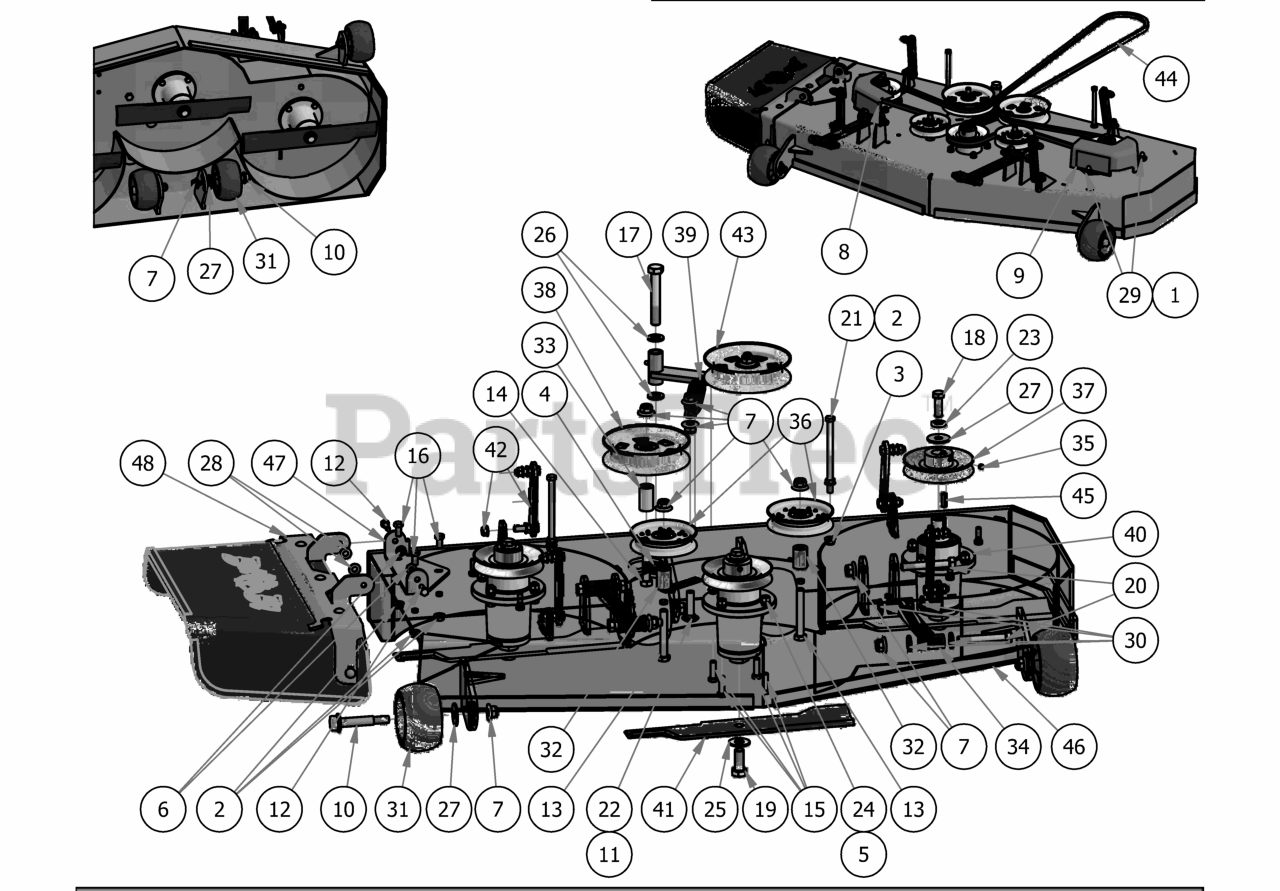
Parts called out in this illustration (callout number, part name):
1	Acorn nut-pulley Cover
2	3/8" Flange Nut
3	3/8" Nylock Flange Nut
4	5/8-11 Nylon Insert Jam Half Nut
5	3/8" Hex Nut
6	5/16" Nylon Flange Nut
7	1/2-13 Nylon Flange Nut
8	pulley cover chute side
9	pulley cover non-chute side
10	Deck Wheel Bolt
11	1/2 x 2" Carriage Bolt
12	5/16-18 x 1 GR 5 Hex Bolt Zinc
13	1/2 x 3 1/2 Flange Bolt Grade 8
14	1/2" x 4" Bolt (Grade 8)
15	3/8" x 1 1/4" Hex Bolt
16	3/8" x 3/4" Hex Bolt
17	5/8" x 4" Hex Bolt
18	1/2"-20 x 1 1/2 - Grade 5 Fine Thread Bolt
19	5/8 x 1 1/2 Grade 8 Hex Bolt (Fine)
20	1/2-13 x 3 1/2 GR 5 Hex Bolt
21	3/8-16 x 5 1/2 Hex Bolt
22	.517 Square Hole Round Washer
23	1/2" Lock Washer Zinc
24	3/8" Lock Washer
25	5/8'' Flat Washer
26	.630 ID Plastic Washer
27	1/2" Belleville Washer
28	.360 ID Plastic Washer
29	.360 ID Plastic Washer-Black
30	.505 Nylon Spacer
31	Deck Wheel
32	Idler Pulley Standoff
33	1 3/4" Pulley Spacer
34	MZ/ZT Deck Locator
35	5/16 Set Screw
36	4 3/4 Idler Pulley - ABFI-76
37	5" Spindle Deck Pulley
38	5-3/4 Idler Pulley
39	Deck Idler Spring
40	Spindle Assembly
41	16 1/4" Bad Boy Blade
42	Deck Hanger Assembly
43	2017 54"/48" Deck Idler Assembly
44	B147 Deck Belt
45	1/4" x 1" Key
46	2017 48" ZT Deck
47	Discharge Chute Hanger (deck mounted)
48	ZT Chute Assembly
